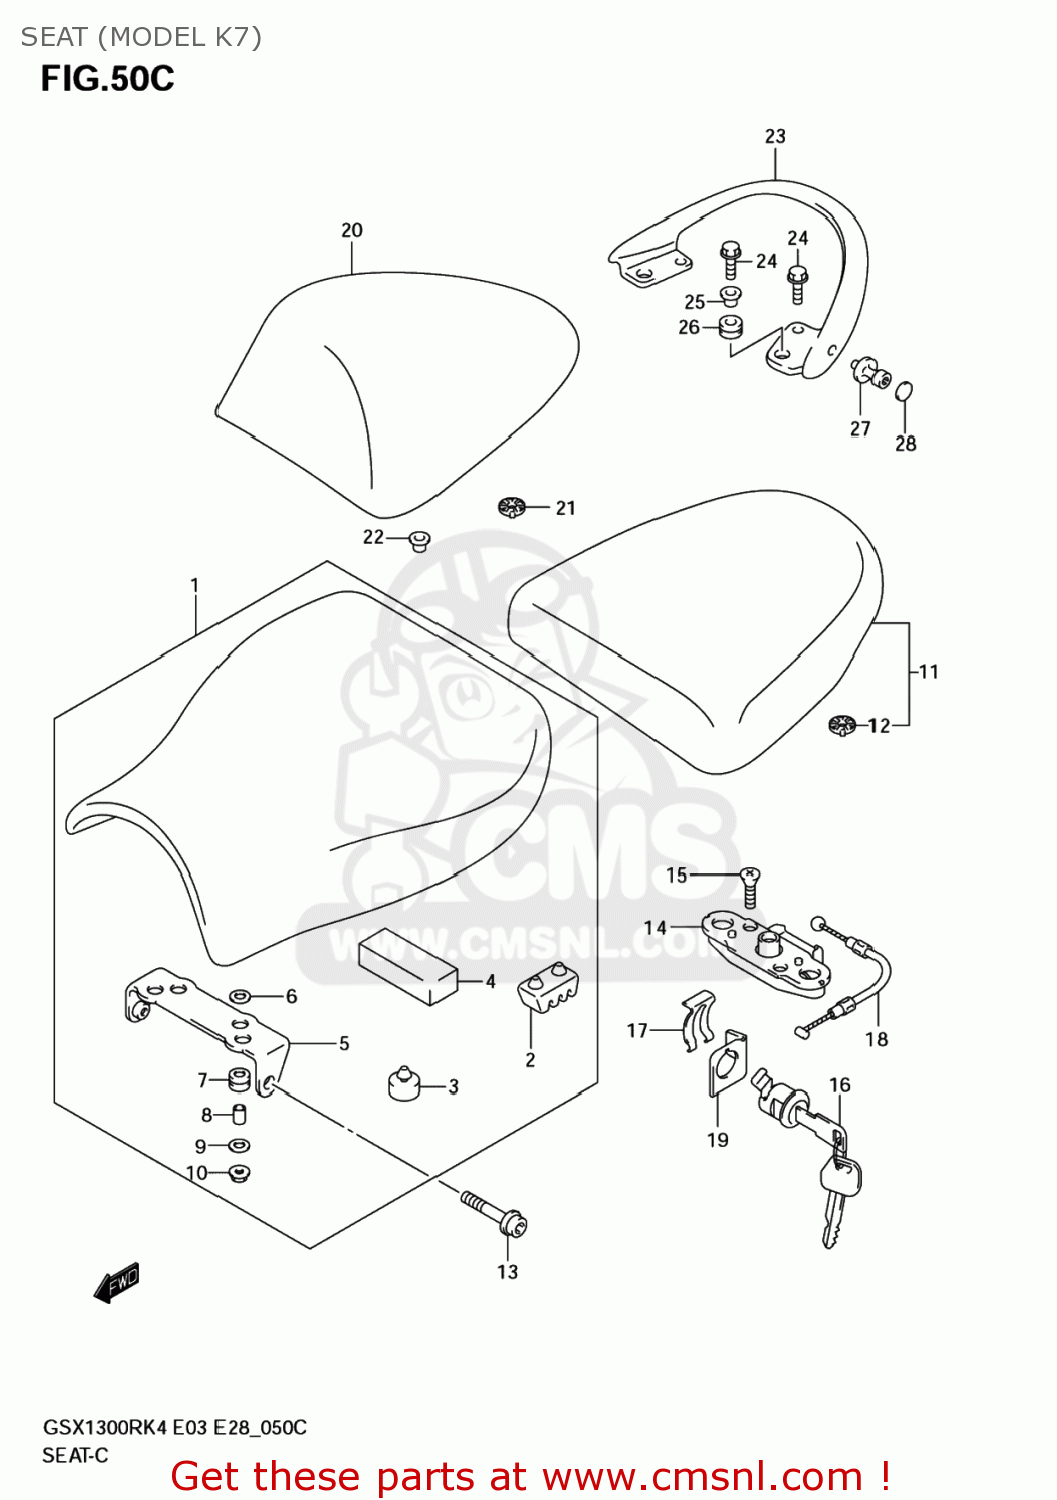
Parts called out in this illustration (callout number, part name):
1	SEAT ASSY(BLACK)
2	CUSHION,SUPPORT(50X25X32)
3	CUSHION
4	CUSHION,CTR
5	BRACKET,SEAT
6	WASHER(6.5X20X1.6)
7	CUSHION,SEAT
8	SPACER(6.5X10X10)
9	WASHER,SEAT BRACKET
10	NUT
11	SEAT ASSY,PILLION
12	CUSHION
13	BOLT,SEAT FR
14	BRACKET,SEAT SUPPORT,RIGHT
15	SCREW
16	LOCK SET,SEAT
17	PLATE,SEAT LOCK ASSY
18	CABLE,SEAT LOCK
19	GUIDE,SEAT LOCK CABLE
20	BOX,SEAT TAIL(RED)
21	CUSHION
22	WASHER COMP,FRAME COVER
23	HANDLE,PILLION RIDER
24	BOLT(8X35)
25	WASHER,PILLION
26	CUSHION,PILLION RIDER HANDLE
27	HOOK,PILLION RIDER HANDLE
28	CAP(OD:10)
